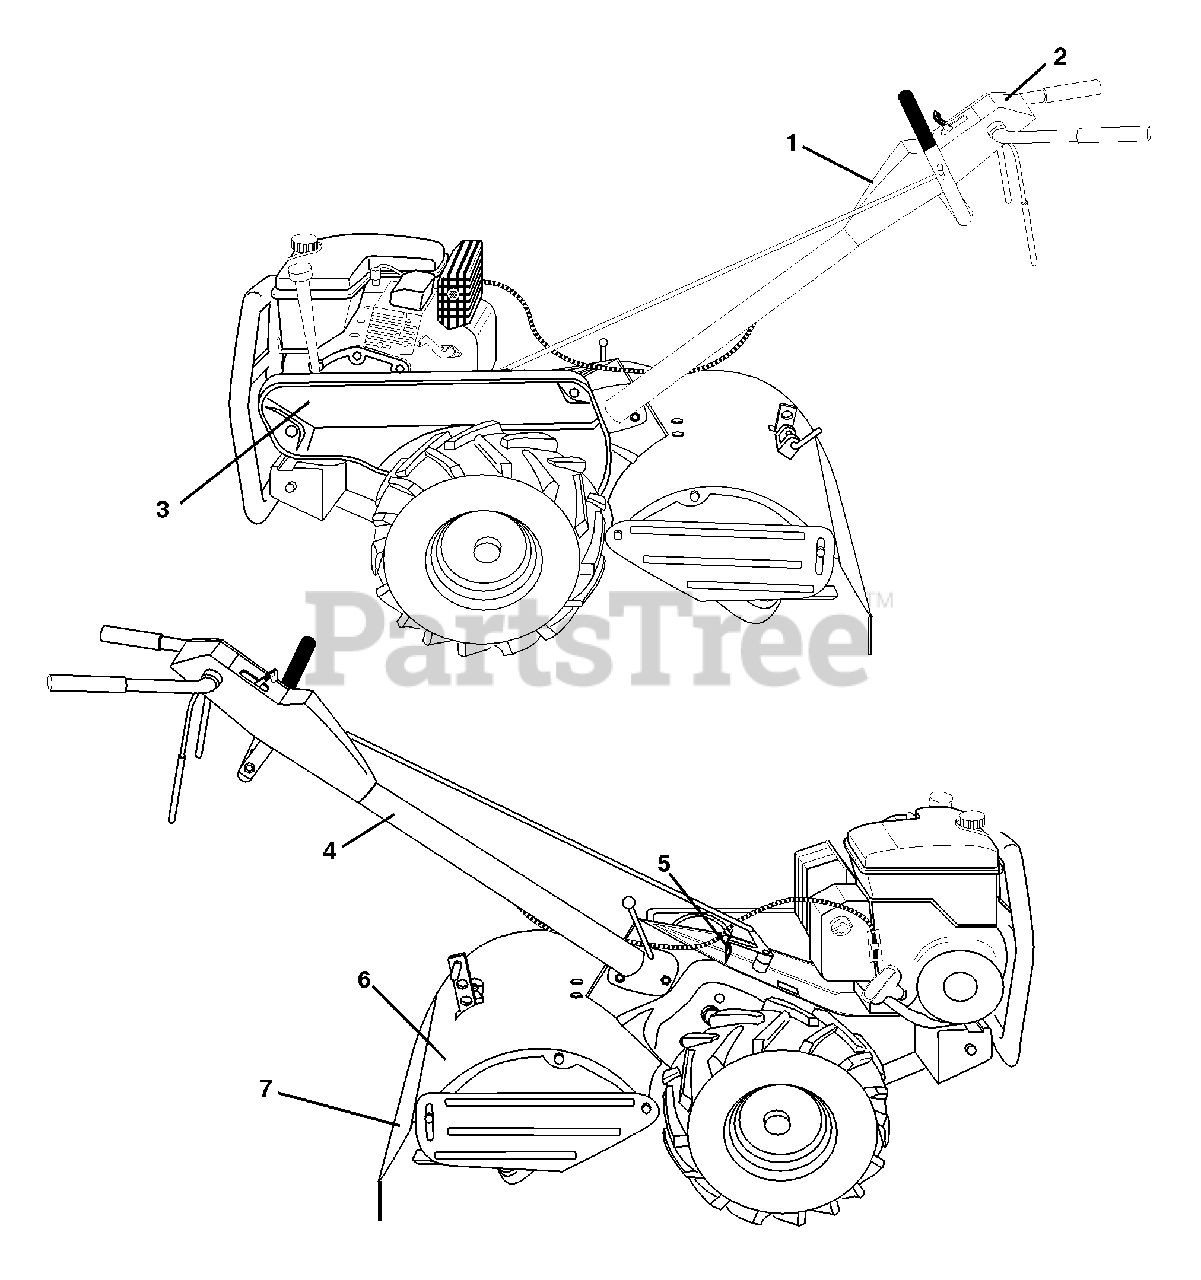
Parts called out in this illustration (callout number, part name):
1	Decal, Logo
2	Decal, Logo
3	Decal, Logo
4	Decal, Hand Placement
5	Decal, Shift Indicator
6	Decal, Caution
7	Decal, Warning, Rotating Tines
